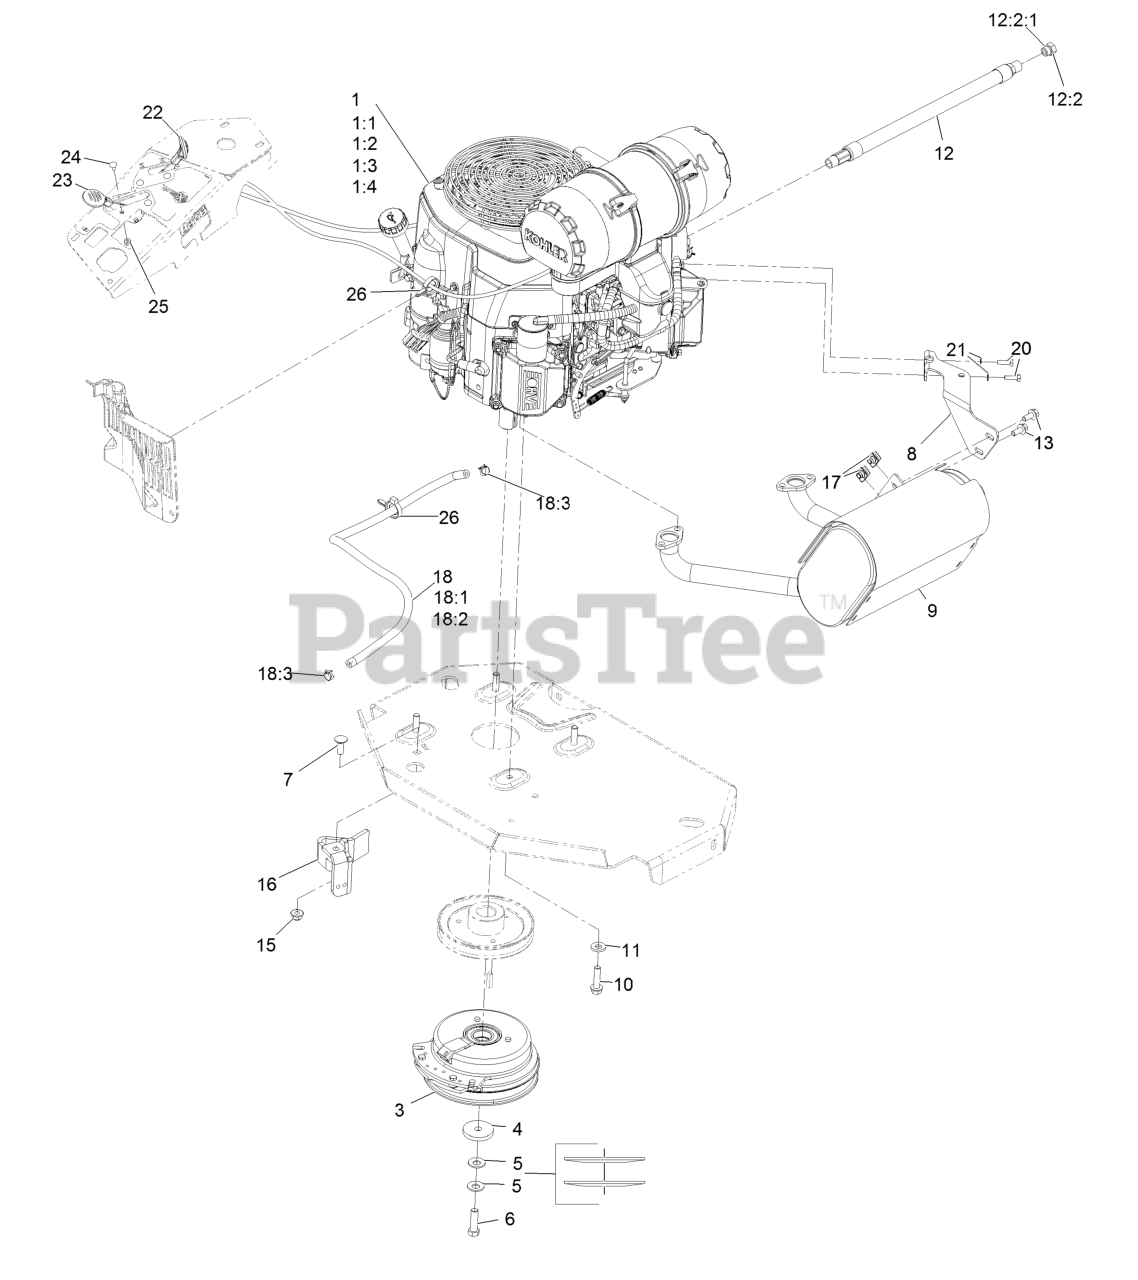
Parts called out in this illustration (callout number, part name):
1:1	Kohler 52 050 02-S Engine Oil Filter
1:2	Kohler 25 083 01-S Engine Air Filter
1:3	Kohler 25 083 04-S Safety Filter
1:4	Kohler 24 050 13-S Fuel Filter
3	Clutch Kit
4	Washer-Clutch
5	Washer-Spring Disc 7/16
6	Screw-HH 7/16-20 X 1 1/2 W/Loctite
7	Bolt-Carriage 3/8-16 X 1
8	Muffler Bracket Kit
9	Muffler Kit
10	Screw-HWH 3/8-16 X 1 1/2 Taptite
11	Washer-Spring Disc 3/8
12	Oil Drain Hose ASM
12:2	Plug-W/O-Ring
12:2:1	O-Ring
13	Screw-HH Flg 5/16-18 X 3/4
15	Nut-Nyloc 3/8-16 Flg
16	Clutch-Anchor
18	Fuel Line ASM
18:1	Hose-Fuel Line 35"
18:2	Sleeve-Thermal
18:3	Clamp-Hose
20	Screw-HH M6-1 X 20Mm W/Patch
21	Washer-Spring Disc 1/4
22	ASM, Choke Cable
23	ASM,Throttle Cable
24	Bolt-Carriage #10-24 X 1/2
25	Nut-Nyloc #10-24
26	Clamp-Hose
